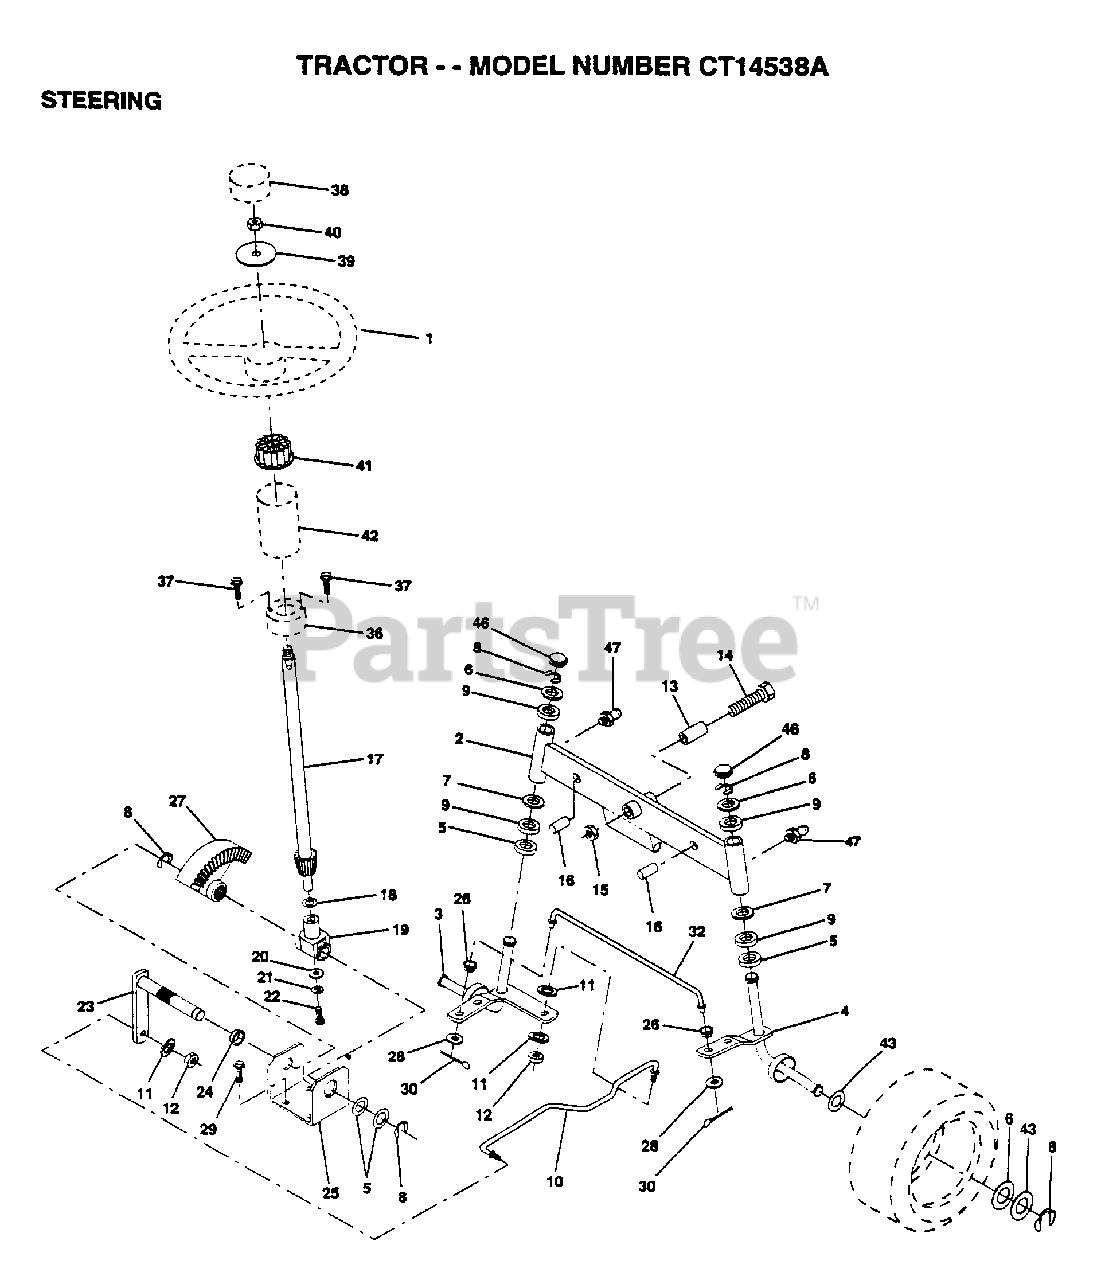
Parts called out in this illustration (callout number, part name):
2	AXLE ASM FRONT
3	SPINDLE LH
4	SPINDLE RH
5	WASHER .T
6	WASHER
7	WASHER
8	RING
9	COL. SRTG. BEAR.
11	LOCKWASHER
13	BEARING
14	BOLT HEX 5/8-11
15	"NUT-LOC,FLANGE LT"
16	AXLE PIN
17	SHAFT ASM
18	THRUST WASHER
19	SUPPORT.SHAFT
21	LOCKWASHER
22	"SCREW,SPECIAL"
24	NYLINER T
25	"BRKT,STEERING"
26	BUSHING.DRAGLINK
27	GEAR SECTOR
28	WASHER
29	SCREW
30	COTTER PIN
32	TIE ROD
38	ST WHL INSERT CAP
39	WASHER T
40	GRIPCO NUT
41	ADAPTER-WHEEL LT
42	"TUBE, STR SHAFT"
43	WASHER
46	CAP
47	ZERK M
